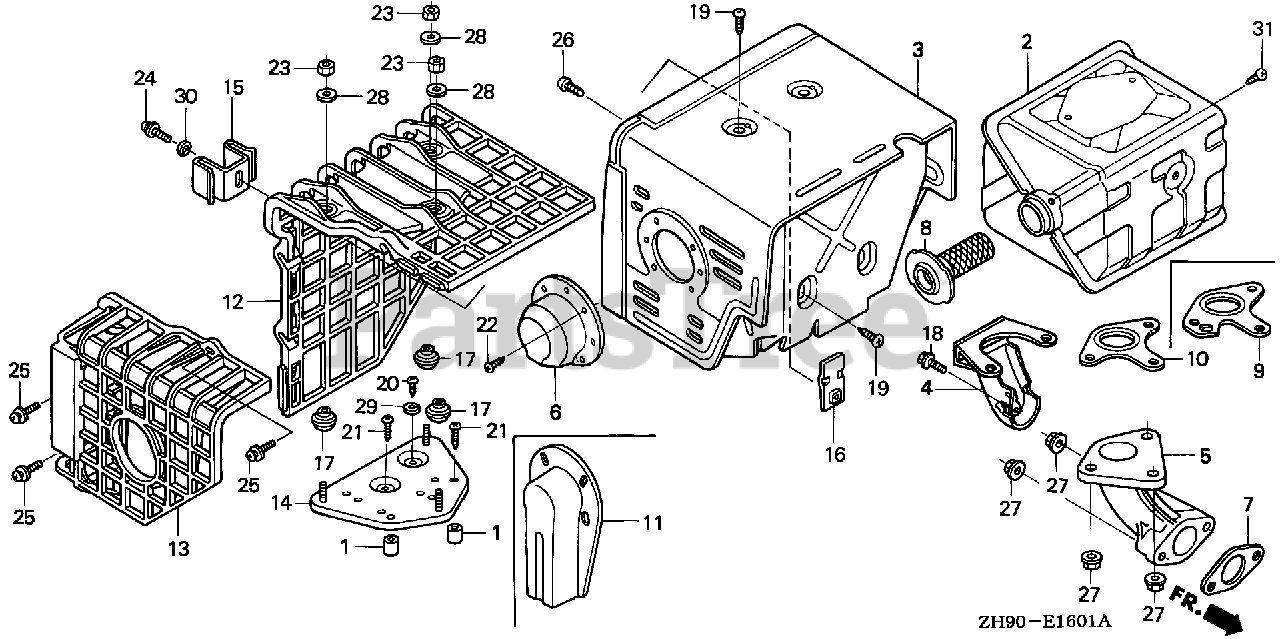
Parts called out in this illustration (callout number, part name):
2	MUFFLER (100DB)
3	PROTECTOR, MUFFLER
4	PROTECTOR, EX. PIPE (100DB)
6	CAP, MUFFLER
7	GASKET, EX. PIPE
8	ARRESTER, SPARK
9	GASKET, MUFFLER (ARRESTER)
18	BOLT, FLANGE (6X12) (CT200)
19	SCREW, TAPPING (5X8)
22	SCREW, TAPPING (4X6) (TO INSTALL OPTIONAL SPARK ARRESTER)
26	SCREW, TAPPING (6X10)
27	NUT, FLANGE (8MM)
31	SCREW, TAPPING (4X6) (TO INSTALL OPTIONAL SPARK ARRESTER)
